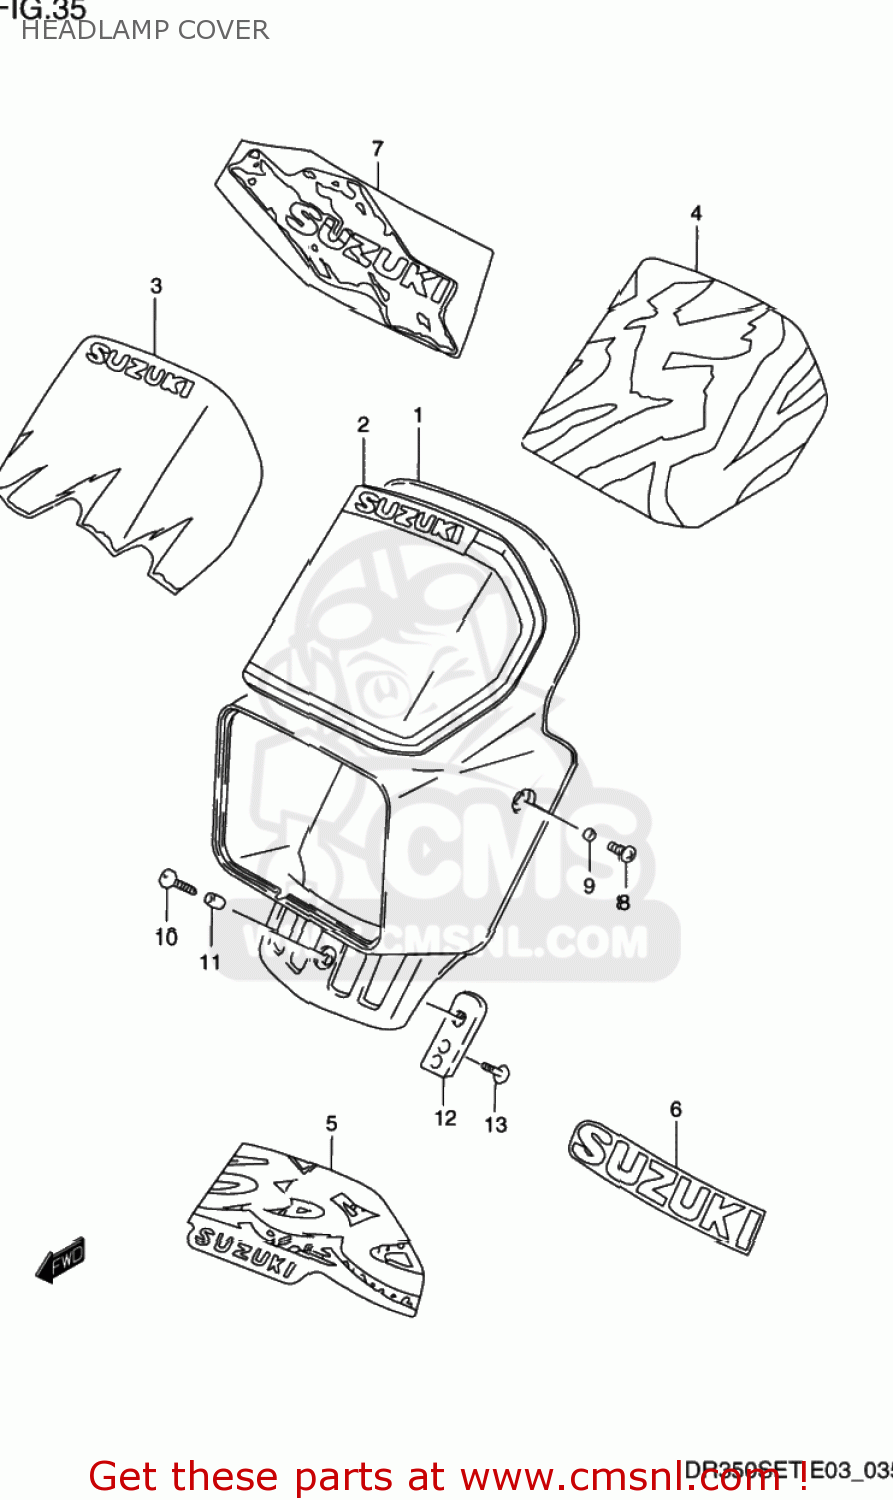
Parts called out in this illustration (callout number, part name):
1	COVER,HEADLAMP
2	TAPE,HEADLAMP COVER
3	TAPE,HEADLAMP COVER
4	TAPE,HEADLAMP COVER
5	EMBLEM,HEADLAMP COVER
6	EMBLEM,HEADLAMP COVER
7	TAPE,HEADLAMP COVER
8	SCREW 6X12
9	SPACER (6.1X8X3.5)
10	SCREW
11	SPACER (6.1X8X12)
12	PLATE,HEADLAMP COVER
13	SCREW
